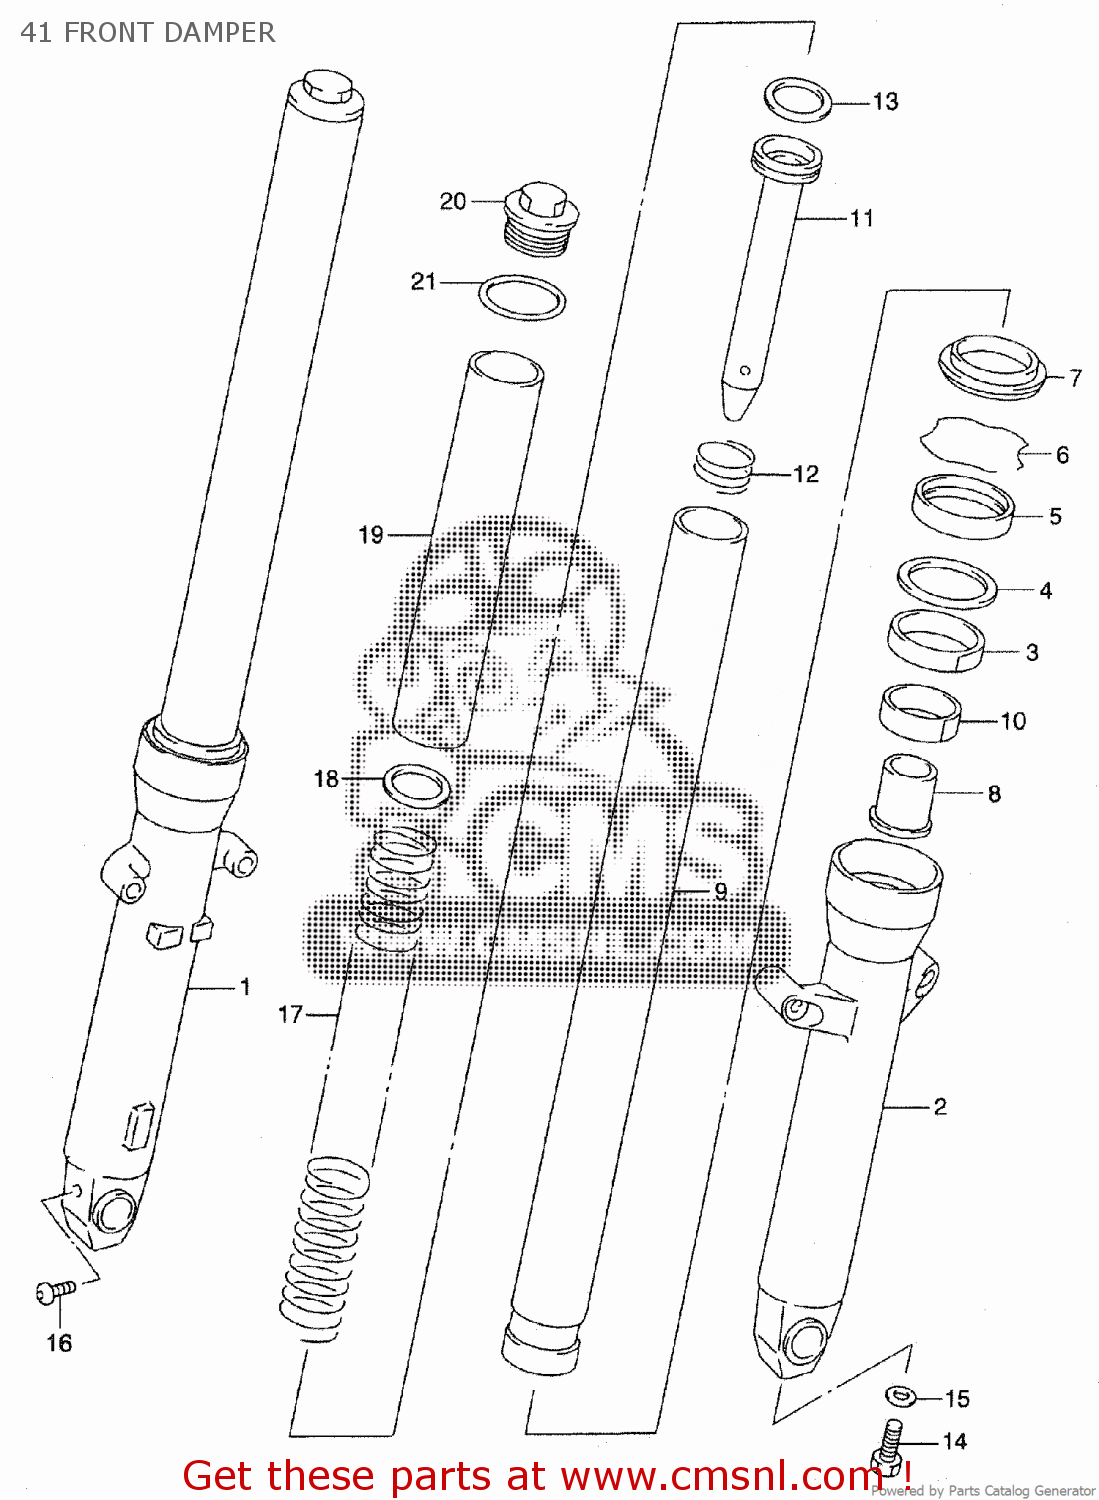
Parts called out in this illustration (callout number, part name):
3	METAL,SLIDE
4	WASHER,FORK OIL SEAL
5	SEAL,OIL
6	RING,OIL SEAL STOPPER
7	SEAL,DUST
8	PIECE,OIL LOCK
10	PISTON
12	SPRING,REBOUND
13	RING,PISTON
14	BOLT,FORK CYLINDER(10X25)
15	GASKET (NAS)
16	BOLT
18	WASHER(22.5X35.9X1.6)
19	SPACER,SPRING
20	CAP,OUTER TUBE
21	O RING(D:3.5,ID:31.7)
